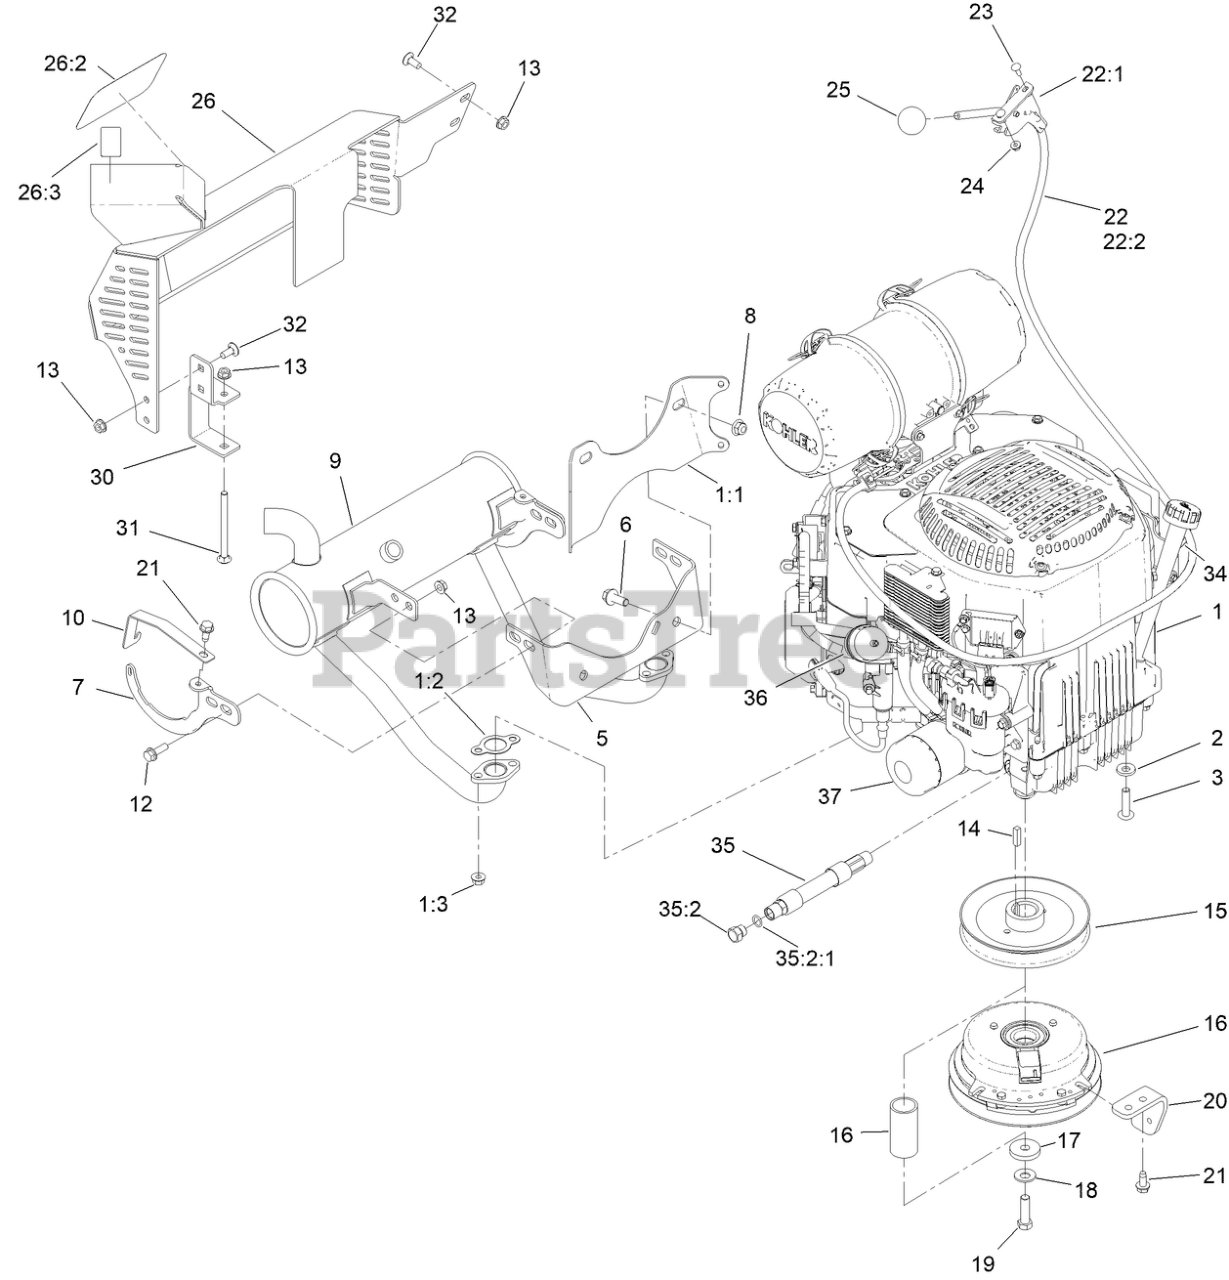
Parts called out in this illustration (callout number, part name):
1:1	BRACKET-MUFFLER
1:2	GASKET-EXHAUST
1:3	NUT-FLANGE
2	WASHER-BELLEVILLE
3	SCREW-BHTF
5	BRACKET-MUFFLER
6	SCREW-HHF
7	SUPPORT-MUFFLER
8	NUT-HF, NI
9	MUFFLER-KOHLER
10	BRACKET-MUFFLER, KOH
12	SCREW-HHF
13	NUT-HF
15	PULLEY
16	CLUTCH
17	WASHER-CLUTCH
18	WASHER-SPRING
19	SCREW-HH
20	STOP-CLUTCH
21	SCREW-HWHTF
22	THROTTLE ASM
22:1	LEVER-CONTROL
22:2	CABLE-THROTTLE
23	BOLT-CARR
24	NUT-LOCK, FLANGE
25	KNOB-BALL
26	MUFFLER GUARD ASM
26:2	DECAL
26:3	DECAL-HOT SURFACE
30	BRACKET-MOUNTING, GUARD
31	SCREW-CARR
32	SCREW-CARR
34	TIE-CABLE
35	HOSE ASM
35:2	PLUG-HH
35:2:1	O-RING
36	FILTER-FUEL
37	FILTER-OIL
